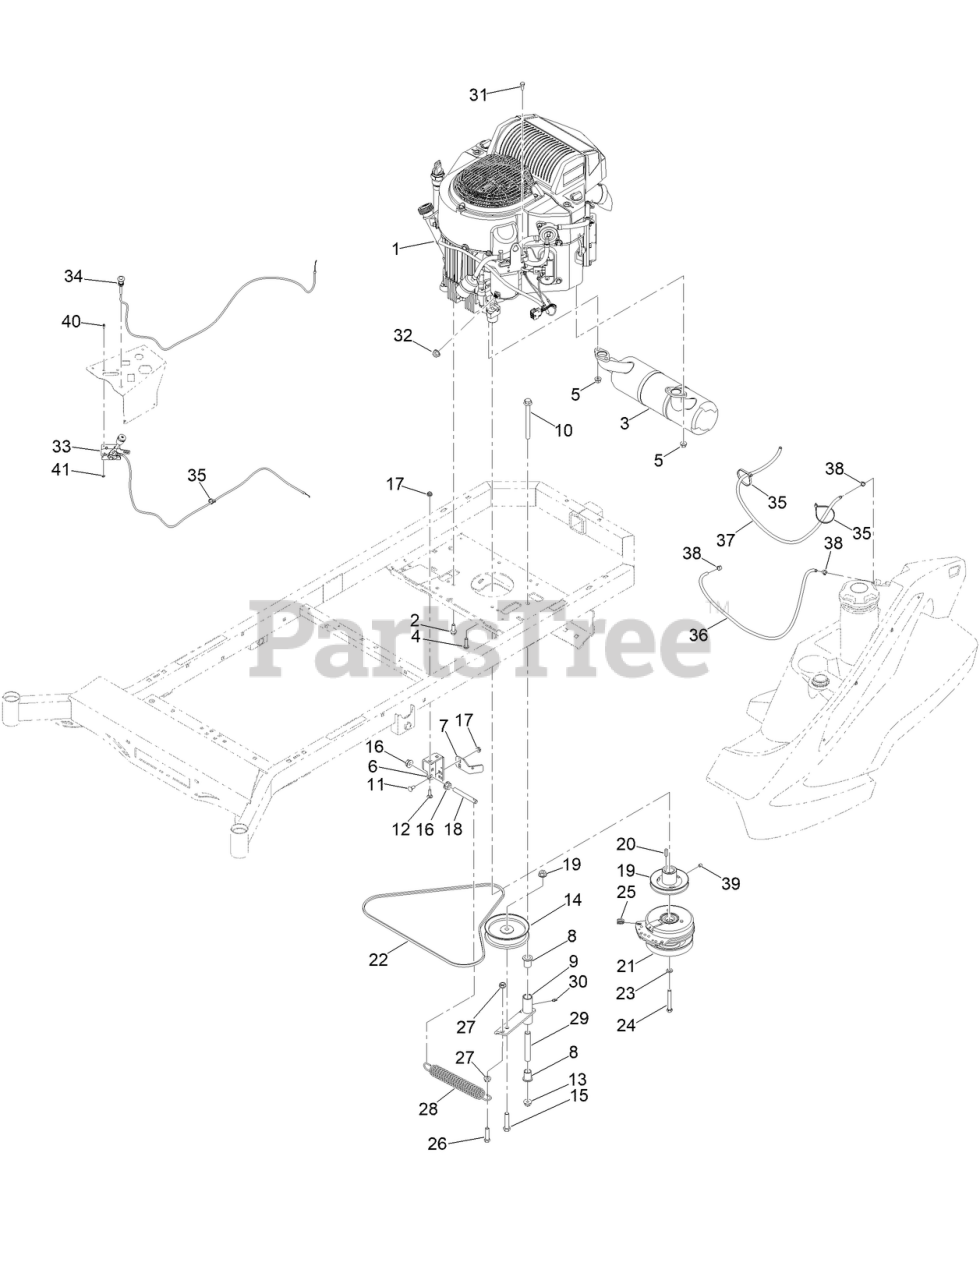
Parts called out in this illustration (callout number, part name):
1	KAWASAKI FT730-CARB ENGINE
2	3/8-16 X 1-1/8 IND HWH W/SERR TRI LOB ZY
3	2019 EXHAUST SYST FOR KAWI FR FS AND FT
4	3/8-16 X 1-1/4 PAN TORX (TRI-LOB) TRS ZC
5	NUT-HF
6	MWR PUMP IDLER TENSIONING BRKT BLACK
7	TTQ 1310 MOWER CLUTCH BRACKET
8	3/4IN ID X15/16IN OD X 1-1/8IN FLNG BUSH
9	MWR PUMP IDLER ASSY BLACK
10	1/2-13 X 5-1/2 HEX FLANGE BOLT GR 8 ZY
11	BOLT-CARR
12	5/16-18 X 1-1/4 CARRIAGE BOLT ZC/YEL
13	NUT-LOCK
14	5-3/4IN IDLER PULLEY 7/16IN SPACER ASSY
15	SCREW-HH
16	NUT-HHF
18	MWR PUMP IDLER SPRING TENSIONER
19	MWR HYDRAULIC PUMP DRIVE PULLEY (B-BELT)
21	WARNER PTO CLUTCH
22	TTQ RT PUMP B-BELT (61.25")
23	WASHER-LOCK
24	7/16-20 X 3 HEX C/S GR 8 ZC YELLOW
25	MWR CLUTCH ROTATION STOP BRKT SLEEVE
26	SCREW-HH
27	NUT-HF
28	MWR DECK SPRING
29	MWR INNER IDLER SPACER
30	1/4IN DRIVE TYPE GREASE FITTING YZ
31	M8-1.25 X 20MM HEX FLANGE BOLT ZINC 10.9
32	1/4-20 HEX FLANGE NUT
33	MWR THROTTLE CABLE ASSY W / HANDLE
34	MWR CHOKE CABLE ASSM
35	TIE-CABLE
36	1/4IN SAE J30R7 BULK HOSE 1FT
37	MWR FUEL TANK BLACK 3/16IN VENT TUBE 1FT
38	1/2IN (#8) HOSE CLAMP
39	5/16-18 X 3/8 SOCKET SET SCREW
40	10-24 X 1/2 SOCKET C/S 18-8 SS
41	NUT-LOCK
